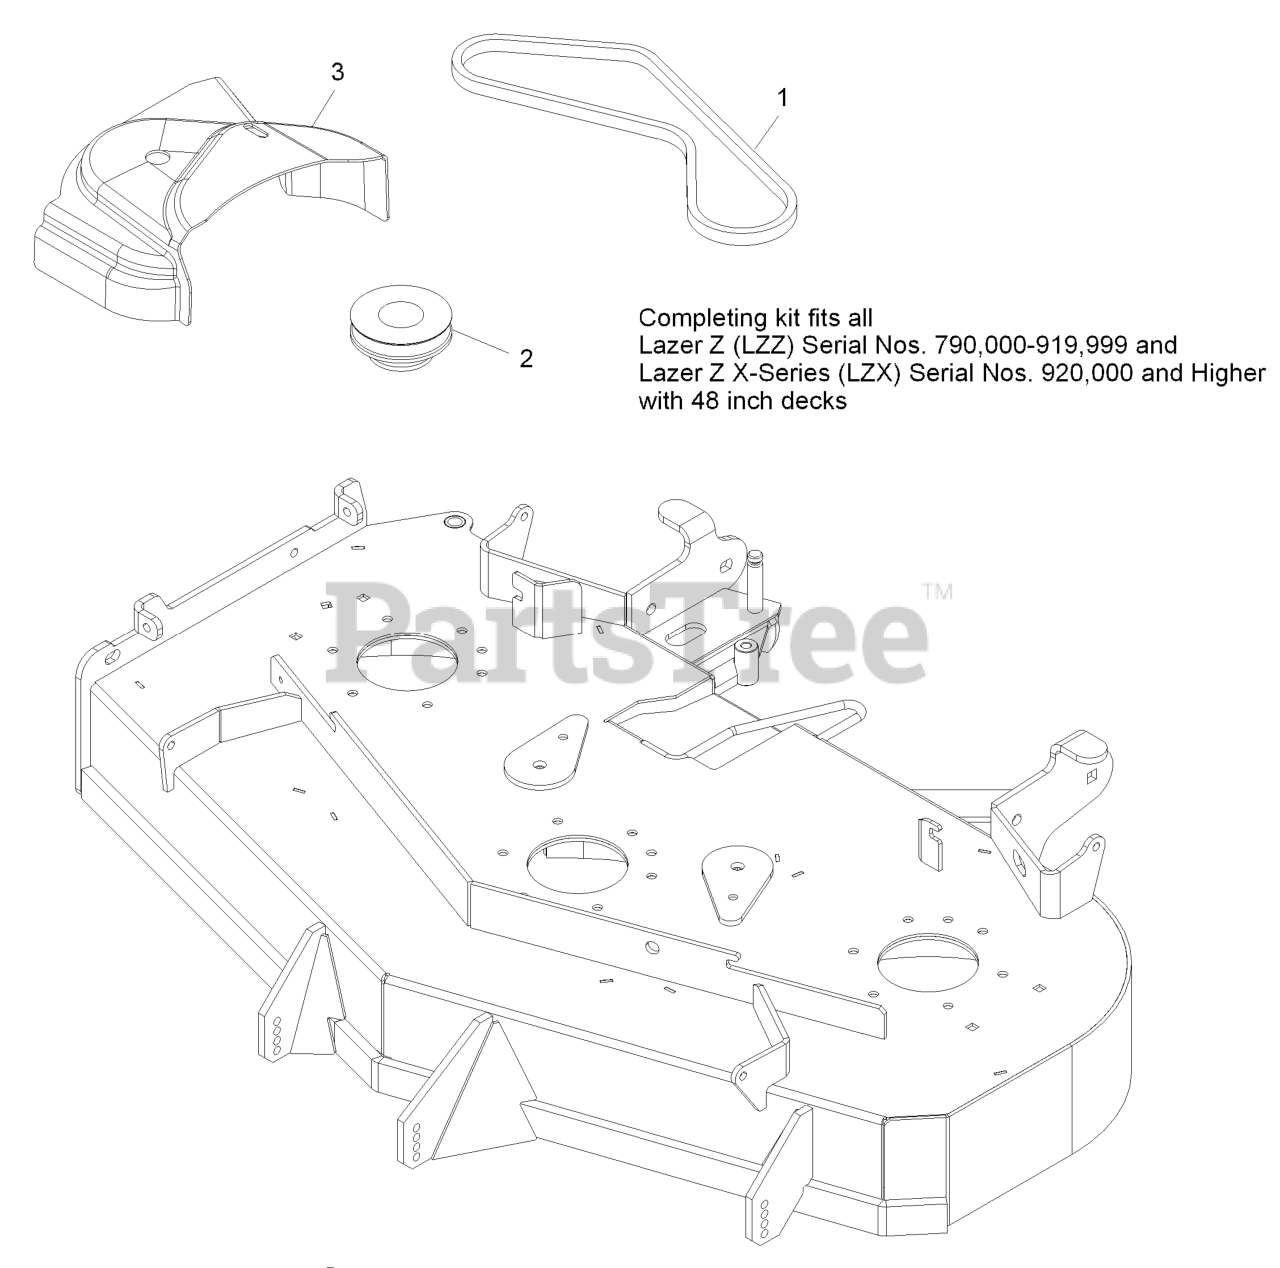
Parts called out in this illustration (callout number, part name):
1	BELT-BLOWER
2	SHEAVE,DRIVE LZUV 486
3	COVER,BELT UV 48
